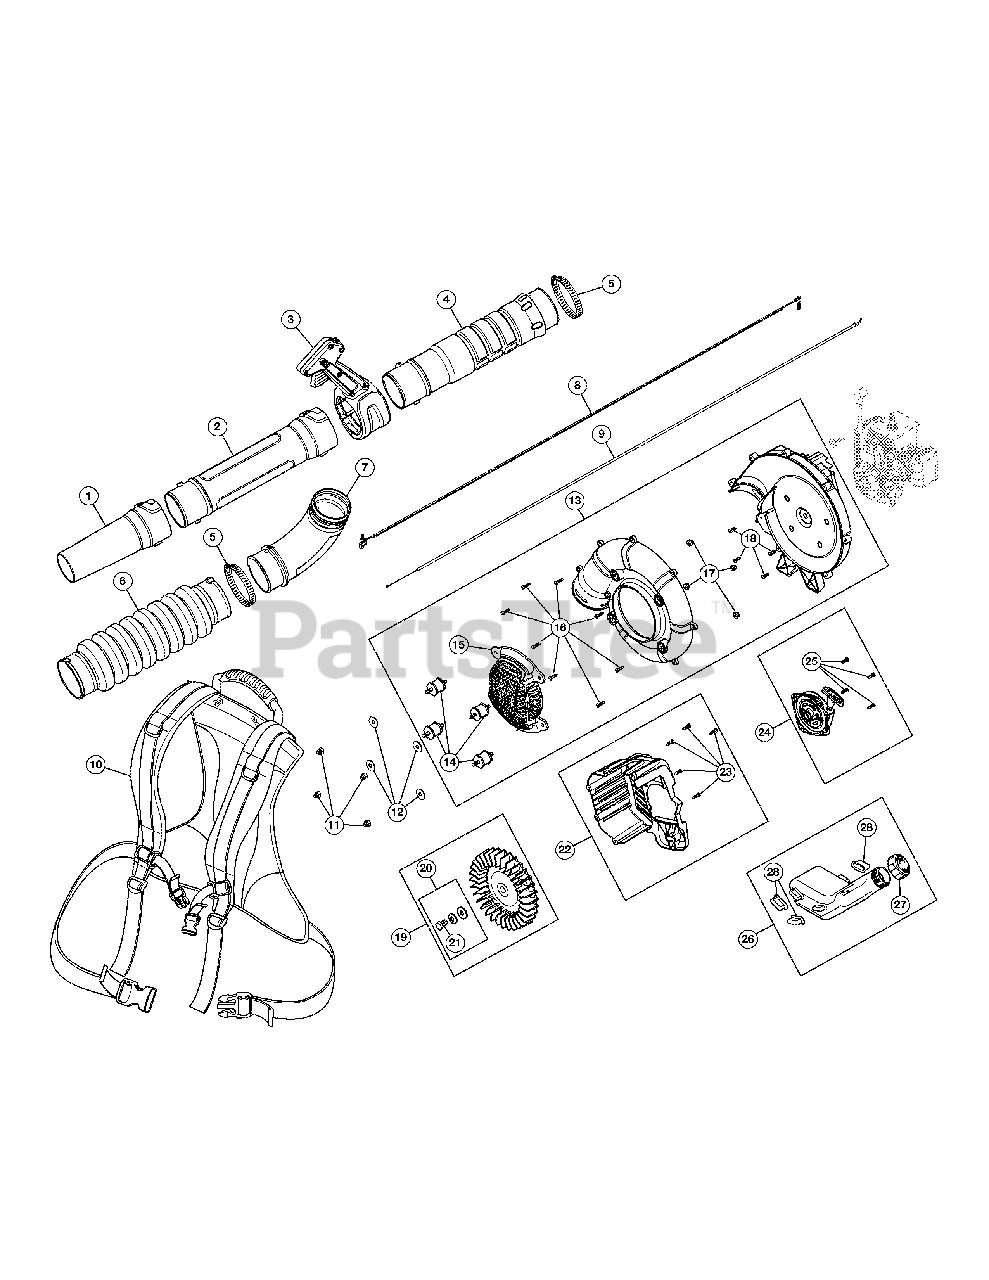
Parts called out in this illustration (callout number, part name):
2	Lower Blower Tube
3	Throttle Grip Assembly
4	Upper Blower Tube
9	Throttle Cable
11	Nut
12	Washer
13	Impeller Housing Assembly (Incl. 14 - 18)
14	Insulator Mount
15	Intake Cover
18	Screw
19	Impeller (Incl. 20 & 21)
20	Impeller Hardware (Incl. 21)
22	Housing Assembly (Incl. 23)
24	Starter Assembly (Incl. 25)
25	Screw
26	Fuel Tank Assembly (Incl. 27 & 28)
28	Fuel Tank Pads
